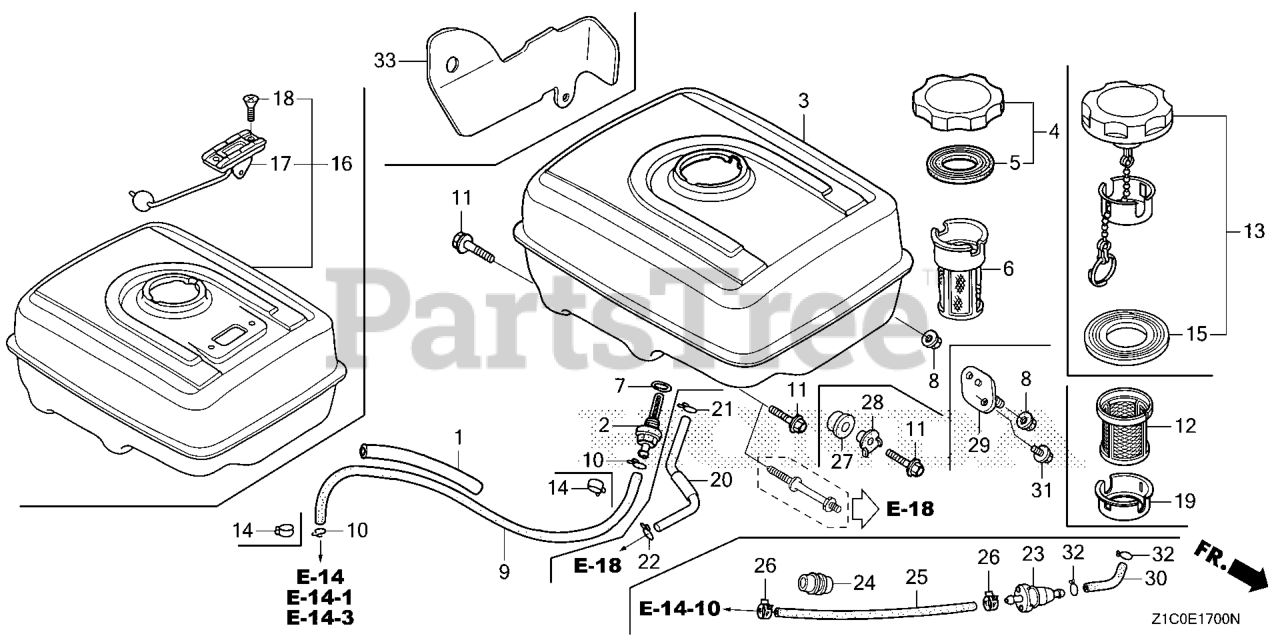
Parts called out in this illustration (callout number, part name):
1	RUBBER, SUPPORTER (107MM)
2	JOINT, FUEL TANK
3	TANK, FUEL *NH1* (BLACK)
3	TANK, FUEL *NH31* (MCKINLEY WHITE)
7	O-RING (14MM) (ARAI) Use up to Engine SN 2949254.
8	NUT, FLANGE (8MM)
9	TUBE, FUEL (4.5X235) (FKM)
11	BOLT, FLANGE (8X25)
13	CAP, FUEL FILLER
14	CLIP, TUBE (D8)
15	GASKET, FUEL FILLER CAP
15	GASKET, FUEL FILLER CAP (39X62X3) (TOUYOUSYA)
